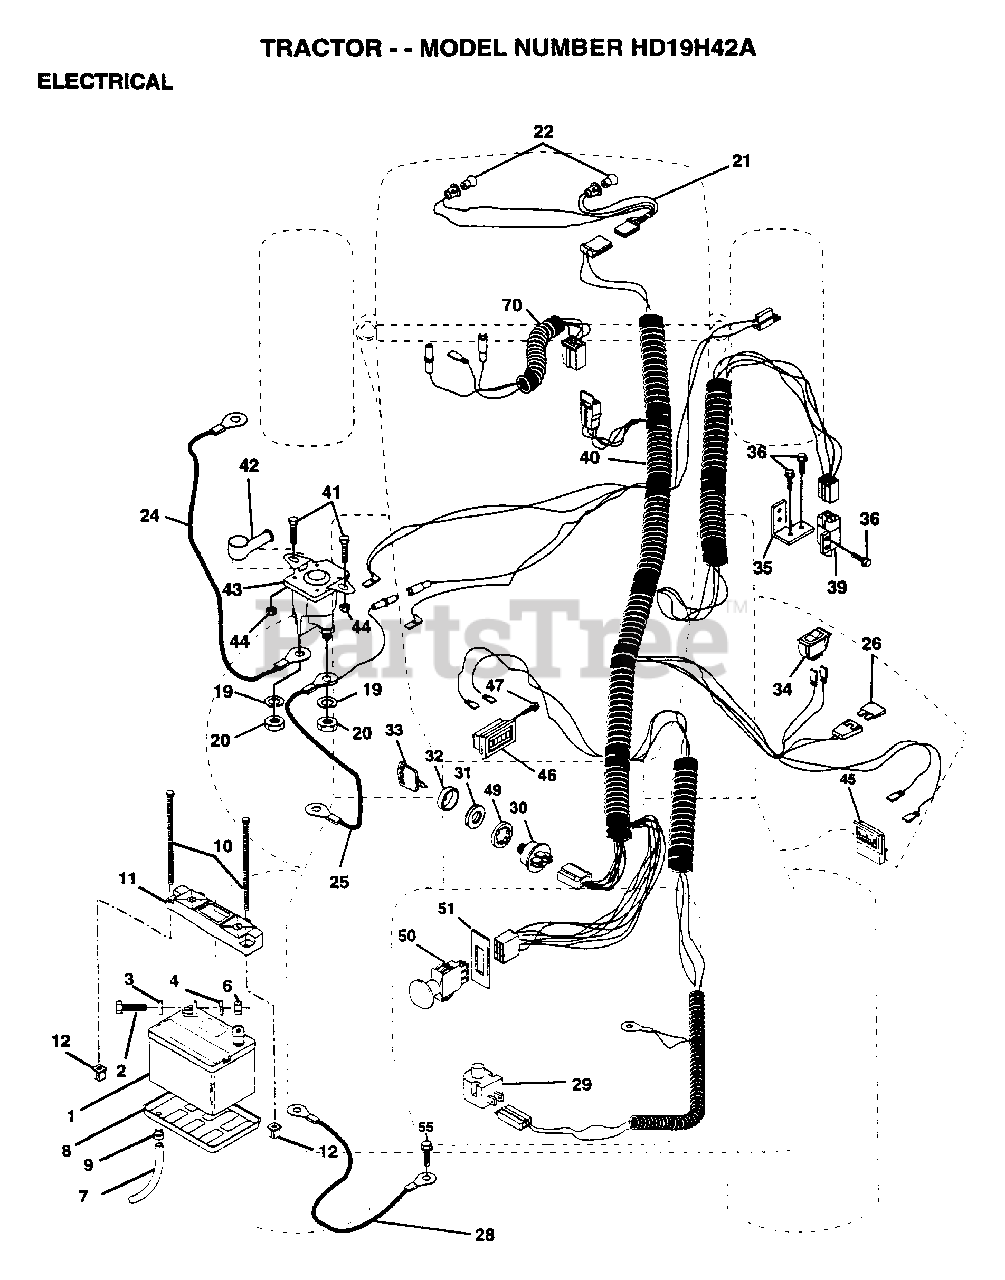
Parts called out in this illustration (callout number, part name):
2	BOLT LT
3	WASHER
4	LOCKWASHER
7	"DRAIN TU T, BATT"
8	"TRAY T, BATTERY"
9	HOSE CLAMP T
20	NUT
21	"HARNESS,LIGHT SOC"
22	HEADLAMP BULB
24	"CABLE T, BATTERY"
25	CABLE.6GA.22W/16W
26	FUSE HYT
28	CABLE.GRND.6GA.21
29	SWITCH SEAT
32	COVER KEY SWITCH
33	KEY MLD GEN DELTA
34	SWITCH LT
35	BRACKET LT
36	SCREW
39	SWITCH INTERLOCKT
40	HARNESS.IGN.ELECT
41	BOLT.HX.1/4-20
44	NUT
45	AMMETER
46	HOUR METER T
47	SCREW
49	LOCKWASHER
51	RING RETAIN PTO
55	SCREW LT
70	HARNESS ENG B&S
